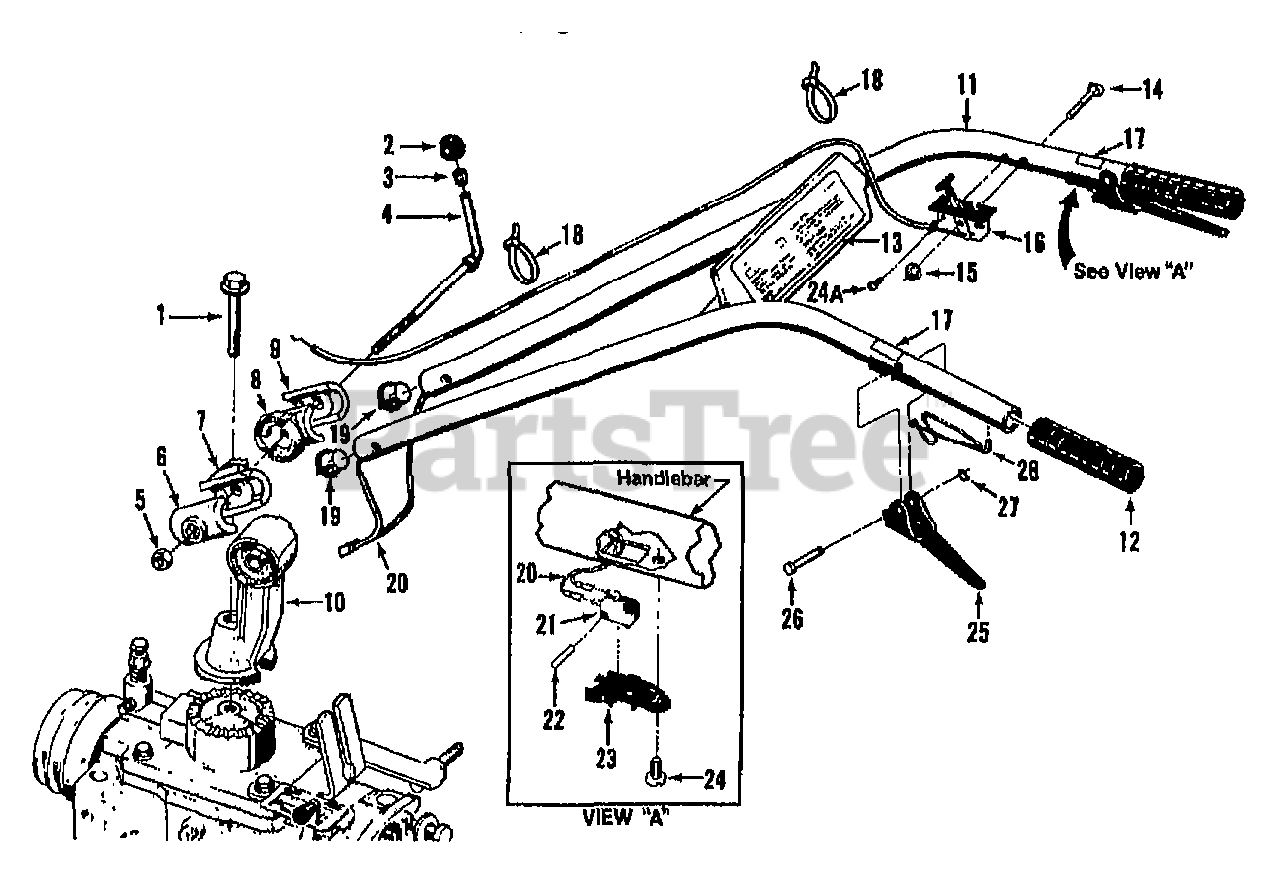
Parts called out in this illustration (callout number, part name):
1	BOLT 1/2-13X3.5 FH GR5
2	KNOB-CONTROL
3	RING-TOLERANCE .5325 ID
4	STUD-H/BAR W/NUT & RING
5	NUT-HEX JAM 1/2-13
6	CLAMP-LH HORSE 1021-1
7	RATCHET-H/BAR RED 2542-1
8	RATCHET-RH RED HORSE 2542-2
9	CLAMP-RH HORSE 1021-2
10	BASE-H/BAR RED 2534A
11	ASSM-HANDLEBAR - INC TWO EA. OF REF. NOS. 12, 17 & 28, AND ONE REF. NO. 13
12	GRIP-H/BAR SMOOTH
13	DECAL-CONTROL PANEL OPC
14	BOLT-CH 1/4-20X2.00 ZP
15	NUT-HF/LK 1/4-20 ZP
16	CABLE-THROTTLE 7 I/C B&S
17	DECAL-FWD INTERLOCK
18	TIE-RED
19	RETAINER-HARNESS H/B OPC
20	HARNESS-WIRE OPC HORSE
21	SWITCH-H/B OPC
22	PIN-LK .11X.58 HORSE OPC
23	HOUSING-SWITCH OPC
24	SCR-HW M10-24X.5 STH ZP
24A	SCR-HW M10-24X.5 STH ZP
25	LEVER-HORSE OPC
26	PIN-PIVOT OPC LEVER
27	RING-KLIP 5304-25
28	SPRING-H/B LEVER
